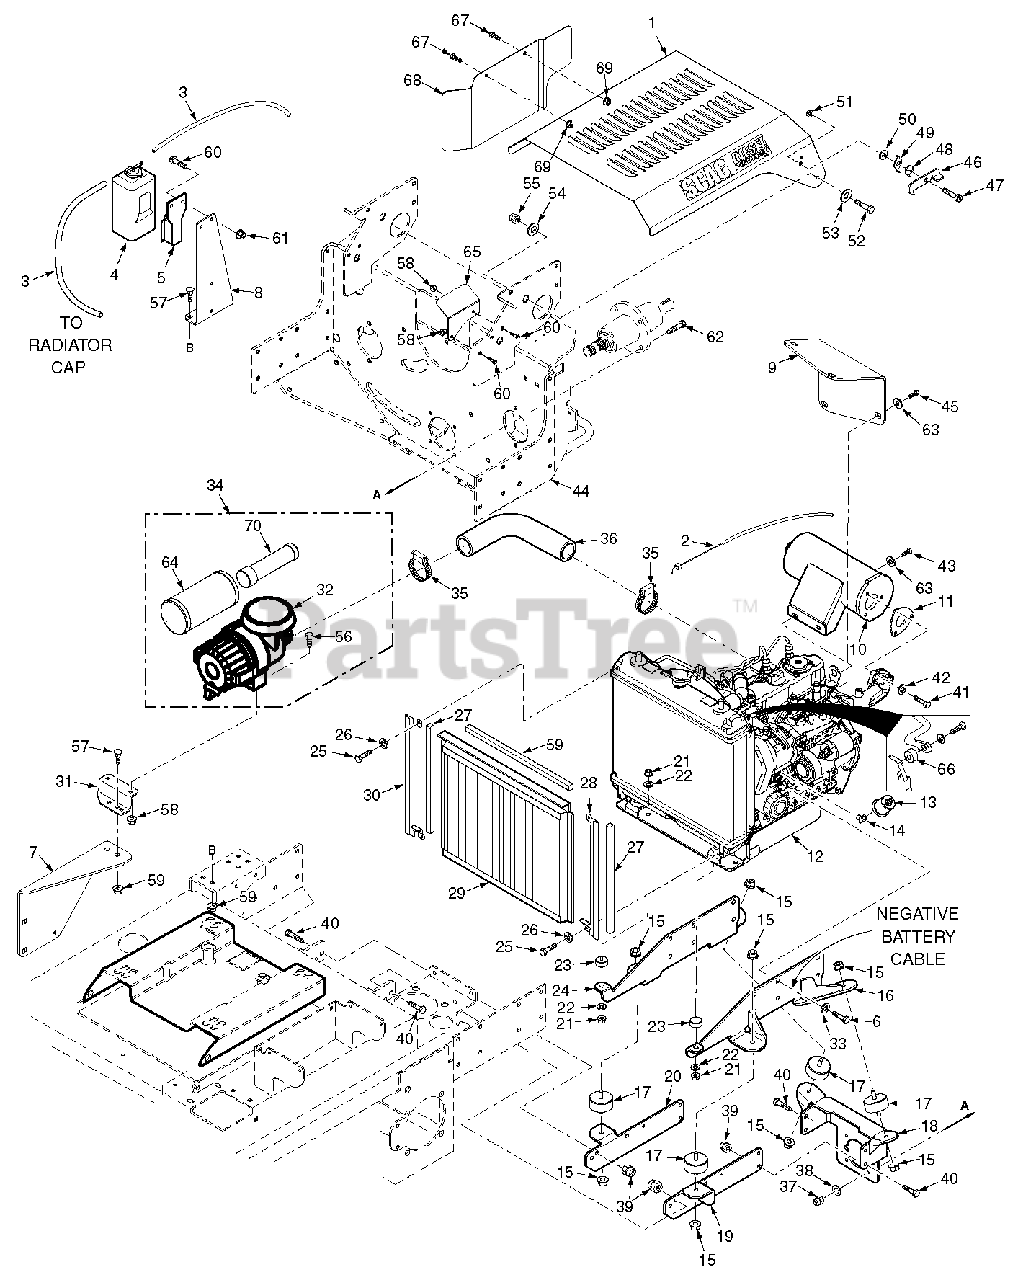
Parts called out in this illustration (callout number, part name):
1	Hood Assembly
2	Throttle Cable
3	Hose, Over Spill Bottle
4	Over Spill Bottle
5	Mounting Bracket, Over-Spill Bottle
6	Bolt, Metric Hex Hd. M10-1.25 x 25mm
7	Bracket, Kubota Air Cleaner
8	Bracket, Kubota Coolant Overflow Bottle
9	Bracket, Kubota Coil
10	Muffler, Kubota
11	Gasket, Muffler
12	Engine, Kubota (not avail. through Scag)
13	Oil Pressure Sender
14	Elbow, 45 Deg.
15	Nut, Serr. Flng. 5/16-18
16	Mounting Bracket Weldment LH
17	ISO Mount
18	Plate, Rear Engine Mount
19	Plate, Engine Mount LH
20	Plate, Engine Mount RH
21	Nut, Metric Hex M8-1.25mm
22	Lockwasher, 5/16" Spring
23	Rubber ISO Mount, Radiator
24	Mounting Bracket Weldment RH
25	Capscrew, Metric M6-1.0 x 16mm
26	Lockwasher, 1/4" Spring
27	Foam, Radiator Screen
28	Debris Screen Track LH
29	Debris Screen Assembly
30	Debris Screen Track RH
31	Bracket, Air Cleaner Mount
32	Rain Cap (Enginaire p/n 68381)
33	Lockwasher, 7/16" Spring
34	Air Filter Assembly (Enginaire p/n 68111)
35	Clamp, 2-1/4" Max. Dia.
36	Hose, Air Intake
37	Nut, Elastic Stop 5/16-18 Grd. 8
38	Lockwasher, 5/16" Spring
39	Nut, Elastic Stop 3/8-16
40	Bolt, Hex Hd. 3/8-16 x 1"
41	Bolt, Metric Hex Hd. M8-1.25 x 30mm
42	Lockwasher, 5/16" Spring
43	Bolt, Metric Hex Hd. M8-1.25 x 25mm
44	Pump Mounting Plate Weldment (Kubota)
45	Bolt, Metric Hex Hd. M8-1.25 x 25mm
46	Latch, Hood
47	Bolt, Shoulder 5/16-18 x 1/2"
48	Spring, Hood Latch
49	Lock, Hood Latch
50	Flatwasher, 3/8 (.391 x .938 x .105")
51	Nut, Center Lock 5/16-18
52	Bolt, Hex Hd. 3/8-16 x 1-3/4"
53	Flatwasher, 3/8 (.391 x .938 x .105")
54	Flatwasher, 3/8 (.406 x 1.50 x 7 Ga.)
55	Nut, Elastic Stop 3/8-16
56	Bolt, Hex Hd. Serr. Flng. 5/16-18 x 3/4"
57	Bolt, Carriage 5/16-18 x 3/4"
58	Nut, Serr. Flng. 5/16-18
59	Foam, Radiator Screen Upper
60	Bolt, Hex Hd. Serr. Flng. 5/16-18 x 3/4"
61	Nut, Serr. Flng. 5/16-18
62	Bolt, Hex Hd. 5/16-18 x 1-3/4" Grd. 8
63	Flatwasher, SAE 5/16 (.344 x .688 x .065")
64	Air Filter, Outer (Enginaire p/n 68300)
65	Shield, Battery
66	Spacer, Radiator
67	Bolt, Serr. Flng 1/4-20 x 3/4"
68	Heatshield, Air Cleaner STT-DF
69	Nut, Serr. Flng 1/4-20
70	Air Filter, Inner (Enginaire p/n 68340)
